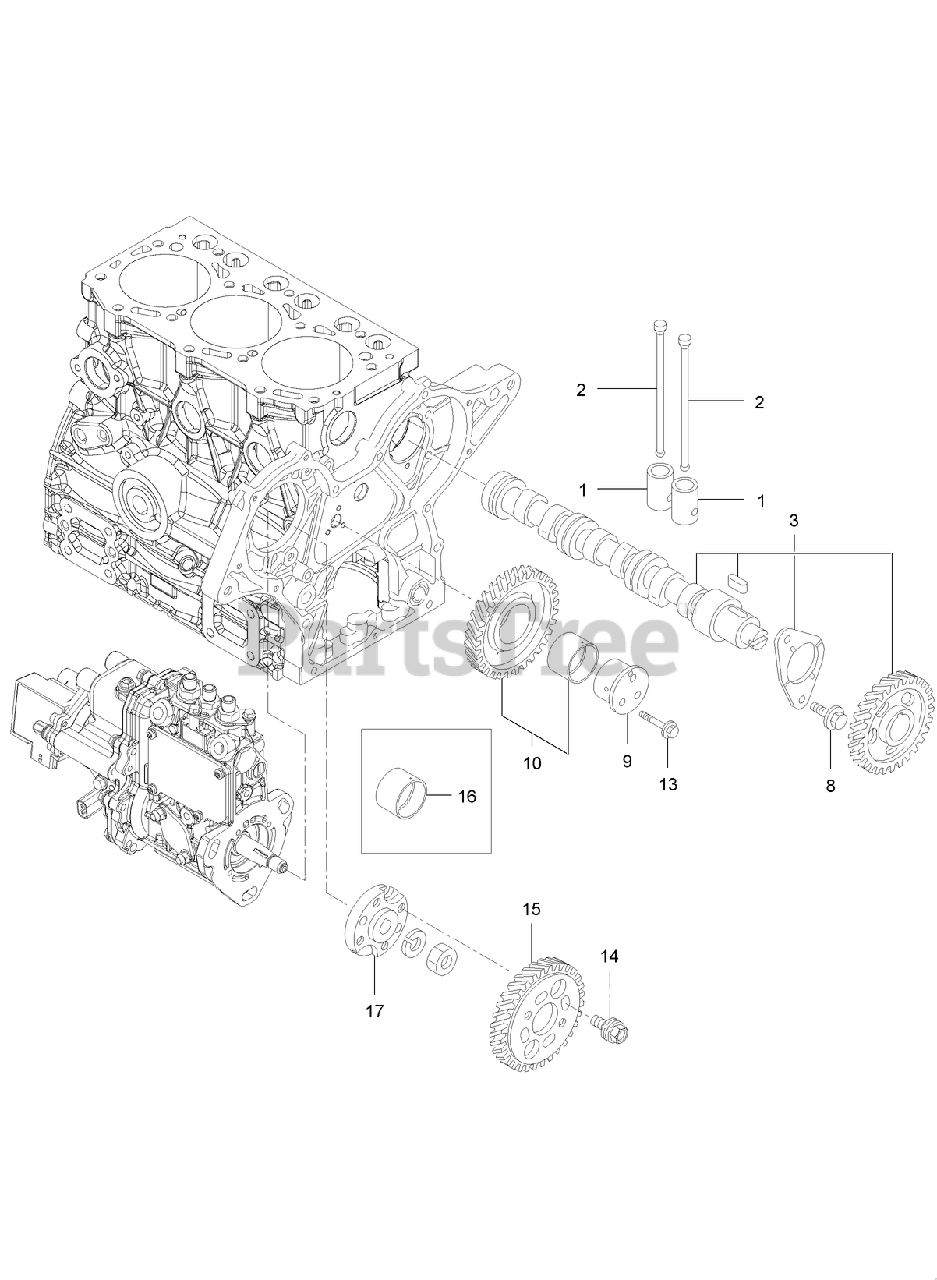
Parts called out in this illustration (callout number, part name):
1	TAPPET
2	PUSH-ROD
3	CAMSHAFT ASM
9	SHAFT-IDLE
10	GEAR ASSY-IDLE
15	GEAR-PUMP
16	BUSH-IDLE GEAR
17	FLANGE
